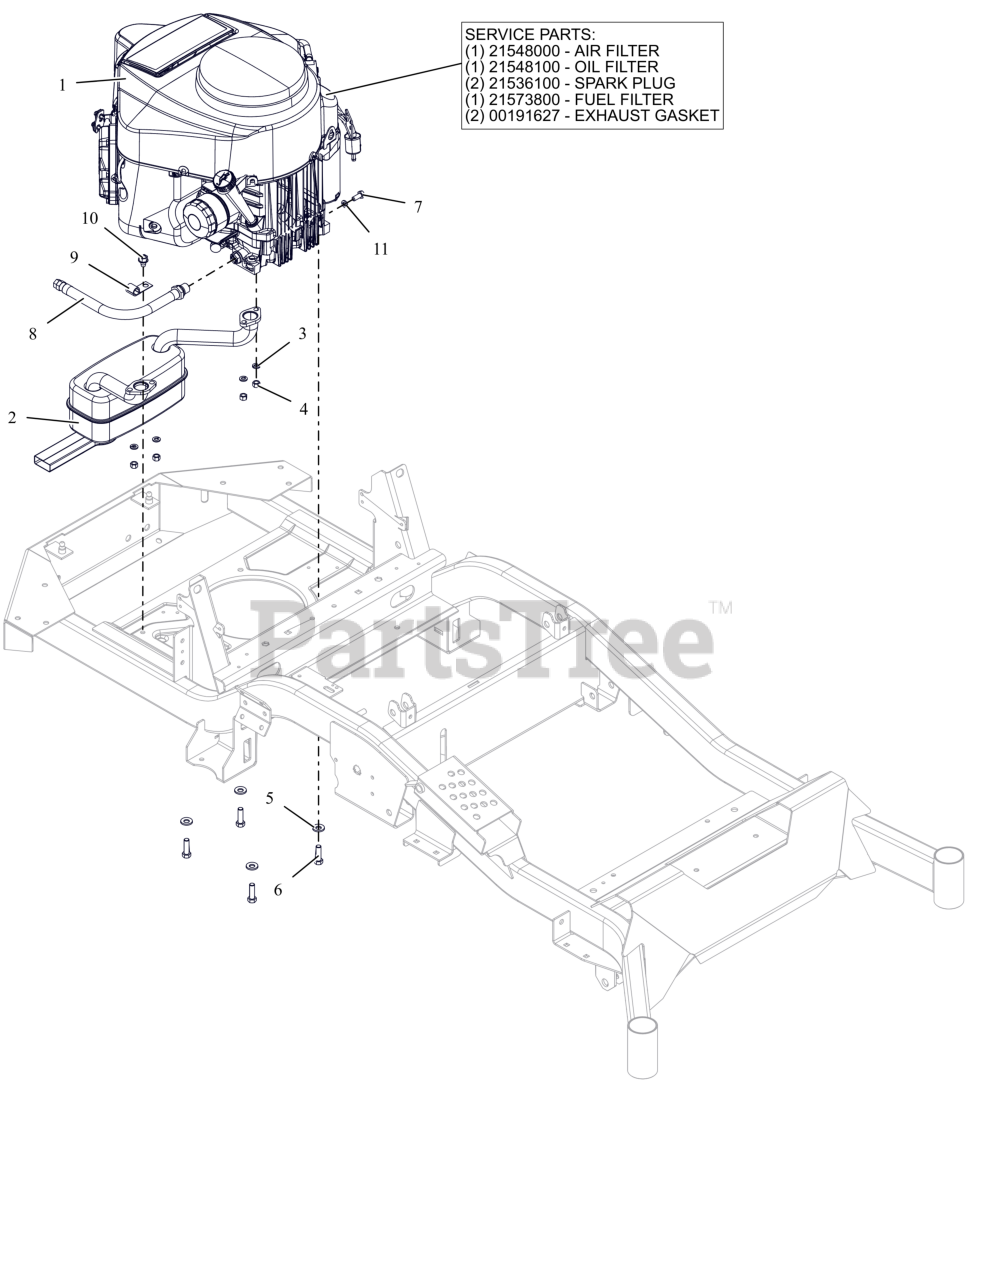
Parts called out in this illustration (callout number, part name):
1	ENGINE, KAWASAKI FR691 23HP
1	AIR FILTER, KAWASAKI FR
1	OIL FILTER, KAWASAKI FR
1	PLUG, SPARK
1	FUEL FILTER-KAWASAKI FR
1	GASKET, MUFFLER S/O
2	MUFFLER, KAWASAKI
3	WSHR,LK-REG .312X.078 ZCC
4	NUT-LK-TOP-FLG M8 ZCC
5	WASHER, 3/8" SPRING DISC
6	BLT, HEX .38-16X1.25 G5 ZCC NT
7	BLT, HEX M8-1.25X20 G8.8 ZCC
8	HOSE, OIL DRAIN
9	J-CLAMP
10	SCR,TAP .375-16X.50 HWH TR ZCC
11	WSHR,LK-REG .312X.078 ZCC
